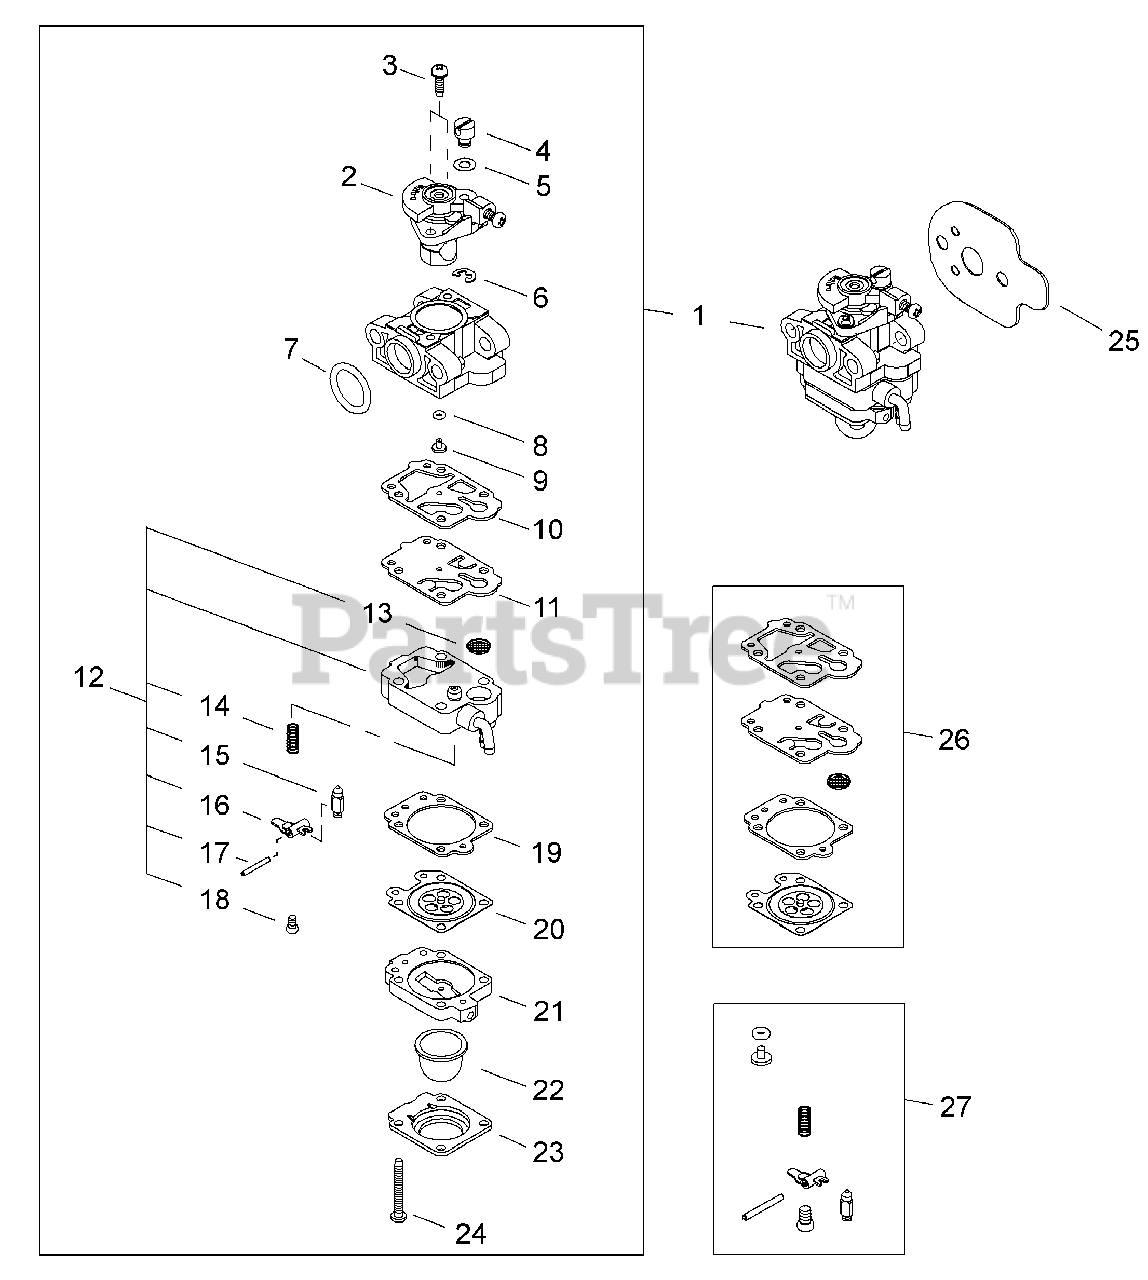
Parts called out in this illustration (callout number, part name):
1	CARBURETOR
2	THROTTLE VALVE ASSY
3	SCREW
4	SWIVEL
5	WASHER
6	RING, RETAINING
7	O-RING - 15
8	O-RING
9	JET, MAIN
10	GASKET, PUMP
11	DIAPHRAGM, PUMP
12	PUMP BODY ASSY
13	STRAINER
14	SPRING, METERING LEVER
15	VALVE, INLET NEEDLE
16	LEVER, METERING
17	PIN, METERING LEVER
18	SCREW, METERING LEVER PIN
19	GASKET, METERING
20	DIAPHRAGM, METERING
21	BASE, PURGE
22	BULB, PURGE
23	RETAINER, PURGE BULB
24	SCREW, PUMP COVER
25	GASKET
26	DIAPHRAGM/GASKET KIT
27	INLET NEEDLE VALVE KIT
